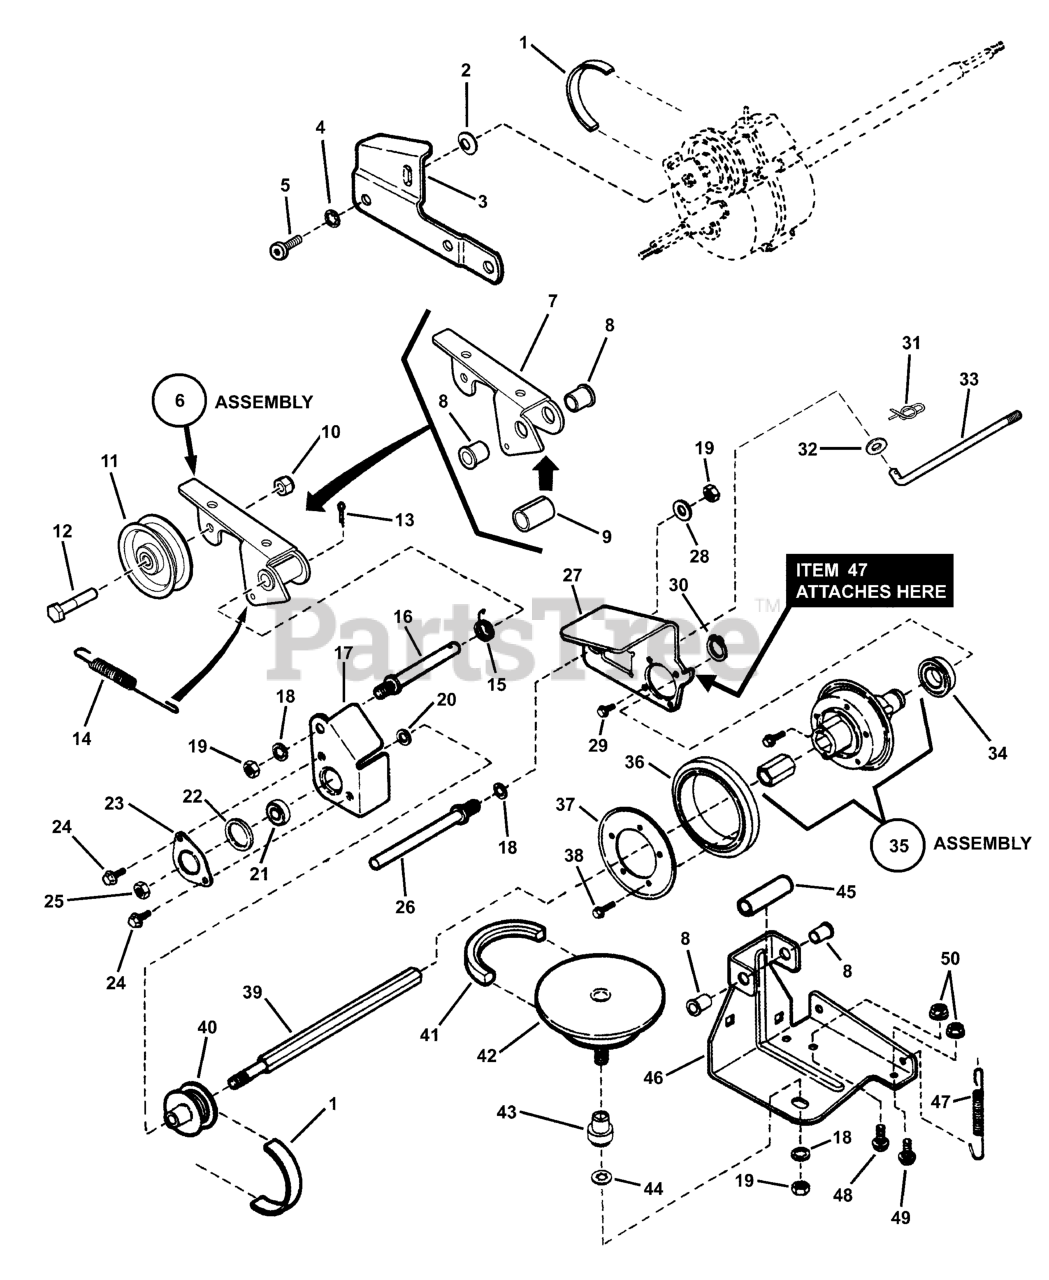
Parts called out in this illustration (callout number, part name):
1	BELT, Poly-V
2	WASHER, 44 x .78 x .025 Curved
3	LINK, Differential
4	WASHER, 5/16" Internal Tooth Lock
5	SCREW, 5/16-18 x 1/2" Pan Head Self-Tap (Torx)
6	ASSEMBLY, Idler Arm, Bushing & Spacer
7	ARM, Clutch Idler
8	BUSHING, Flange (Powdered Metal)
9	SPACER, Idler Arm
10	NUT, 1/4-28 Hex Top Lock
11	PULLEY, Idler
12	SCREW, 1/4-28 x 1-3/8" Hex Head Cap, GR 5
13	COTTER PIN, 3/32 x 1/2"
14	SPRING, Clutch- 21S
15	SPRING, Idler- Torsion
16	STUD, Idler (3/8-24 thread)
17	HOLDER, Bearing (Inner Half)
18	WASHER, 3/8" Internal Tooth Lock
19	NUT, 3/8-24 Hex
20	WASHER, 3/8" Flat
21	BALL BEARING, Spherical O.D., .38 I.D.
22	O-RING
23	HOLDER, Bearing (Outer Half)
24	SCREW, 1/4-20 x 1/2" Hex Flange Self-Tap
25	NUT, 3/8-24 Hex Center Lock, GR 5
26	GUIDE, Thrust Plate (3/8-24 thread)
27	THRUST PLATE, Short
28	WASHER, 3/8" Flat
29	SCREW, #10-32 x 1/4" Self-Tap Machine
30	RETAINING RING, .625 External
31	COTTER PIN, .06 x .50
32	WASHER, .28 x .63 x .06 Flat
33	LINK, Transfer (1/4-28 thread)
34	BALL BEARING, 3/4" Bore- Commercial
35	KIT, Driven Disc Bushing & Hub
36	DRIVEN RING, 21P
37	PLATE, Ring Retaining
38	SCREW, #10-24 x 1/2" Self-Tap Machine
39	SHAFT, Hex (3/8-24 thread, one end)
40	PULLEY, Poly-V (2.00" O. D.)
41	BELT, Engine Drive (Stretch)
42	ASSEMBLY, Steel Drive Disc
43	BUSHING, Powdered Metal
44	RETAINER, 5/16" Bolt
45	SPACER, .500 x .65 x 1.75
46	BRACKET, Deck, P21S
47	SPRING, Wheel Drive
48	BOLT, 5/16-18 x 1/2", Short Neck Carriage, GR 5
49	BOLT, 5/16-18 x 5/8" Short Neck Carriage, GR 5
50	NUT, 5/16-18 Hex Flange Lock GR 5
